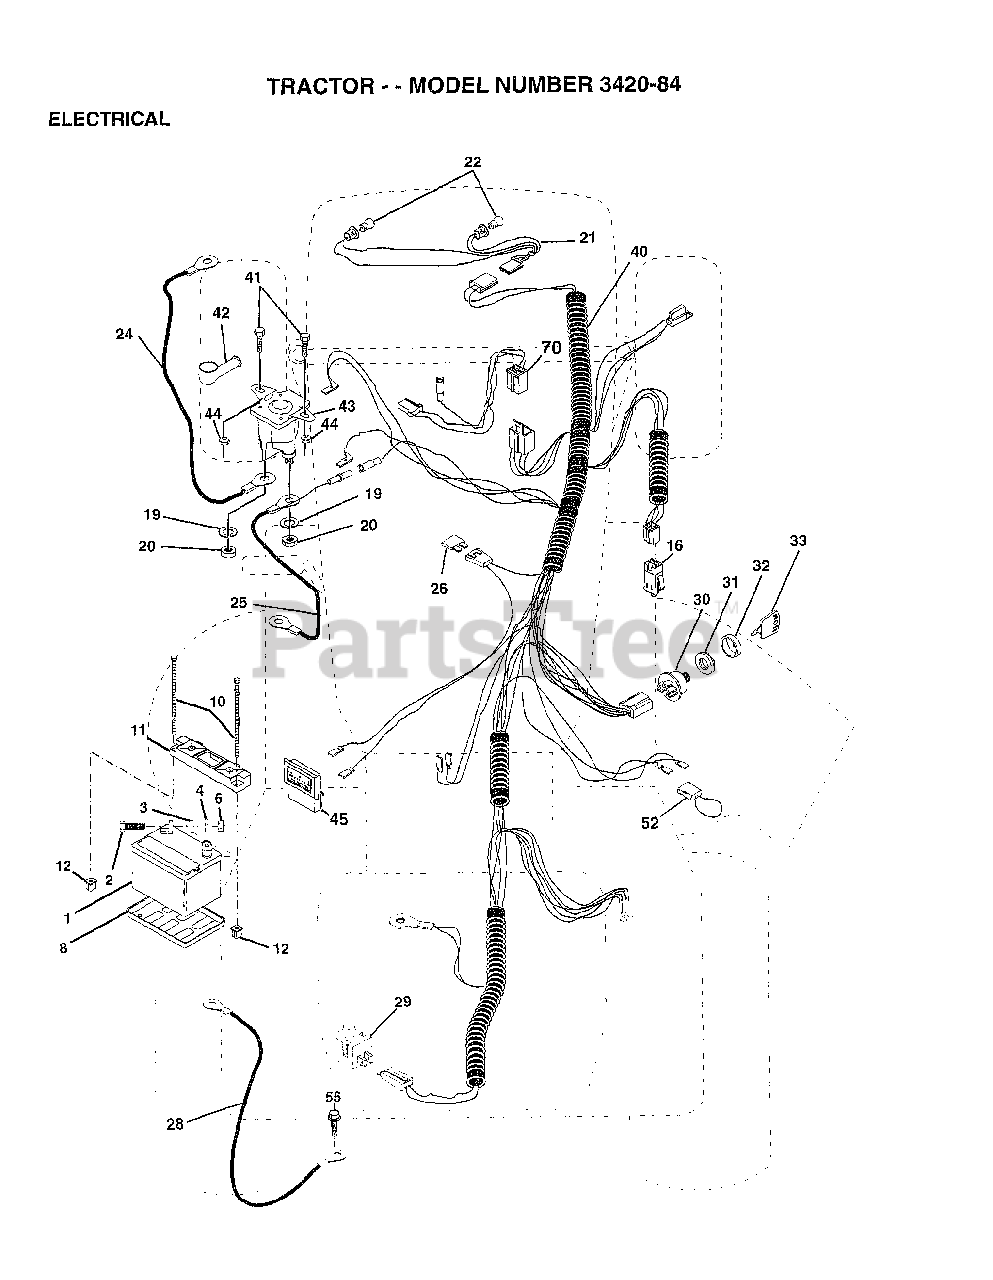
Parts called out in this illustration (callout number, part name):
3	WASHER
4	LOCKWASHER
8	"TRAY T, BATTERY"
11	HOLDDOWN BATTERY
16	SWITCH INTERLOCK
20	NUT
21	"HARNESS,LIGHT SOC"
22	HEADLAMP BULB
24	"CABLE T, BATTERY"
25	CABLE.6GA.22W/16W
26	FUSE HYT
28	CABLE.GRND.6GA.21
29	SWITCH SEAT
30	SWITCH IGN 4POS
31	NUT IGNITION
32	COVER KEY SWITCH
33	KEY
40	"HARNESS-IGN,YDPRO"
41	BOLT HXHD FIN
44	NUT HXKEP 1/4X20
52	PROTECTION LOOP
55	SCREW LT
70	HARNESS ENG DUAL
